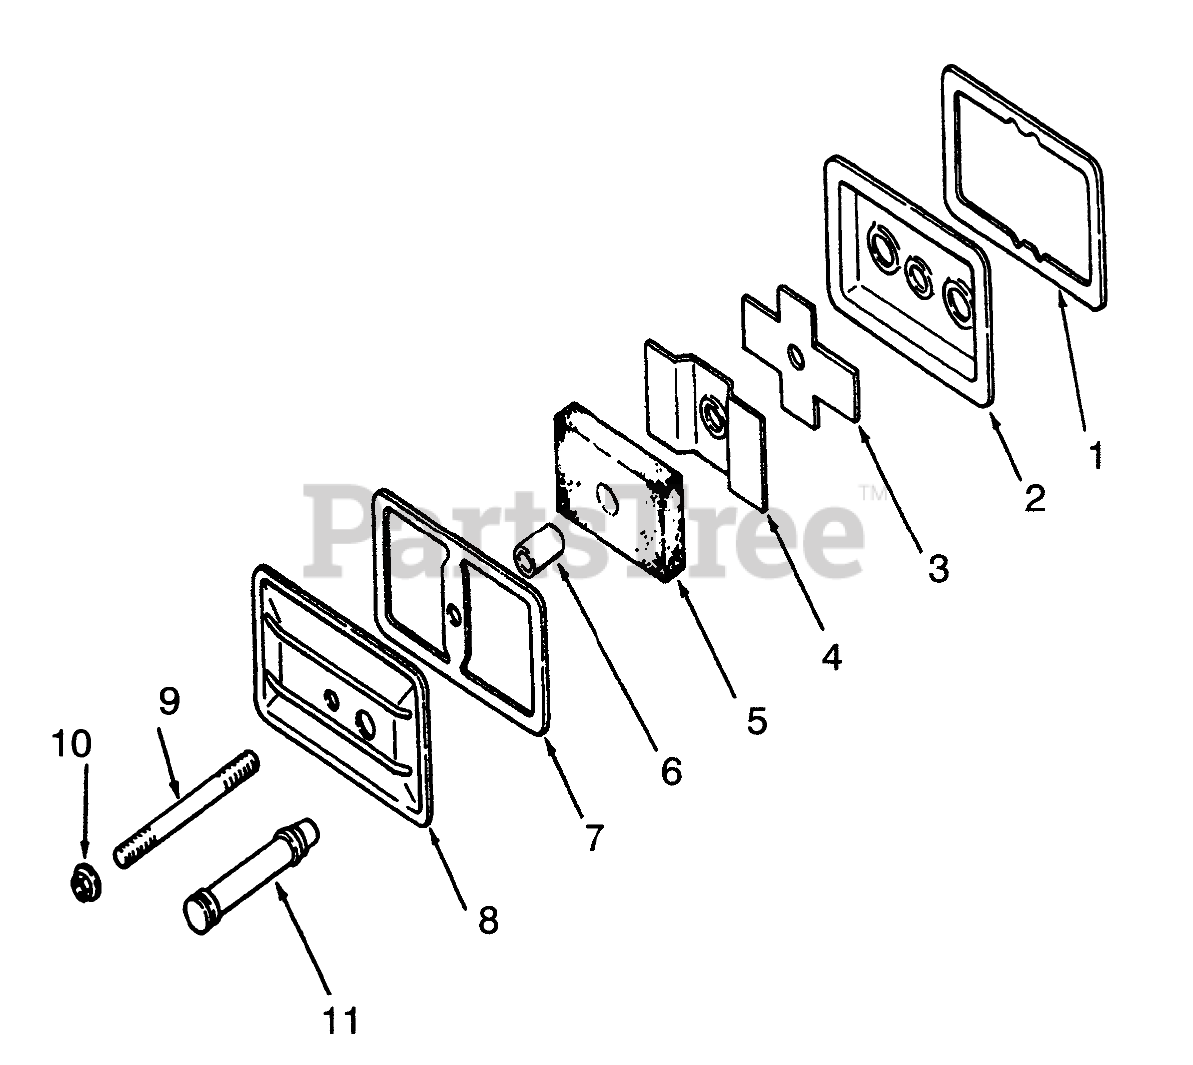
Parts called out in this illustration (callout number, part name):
1	Gasket
2	Plate
4	Baffle
5	Filter
7	Gasket
8	Cover
10	Palnut
